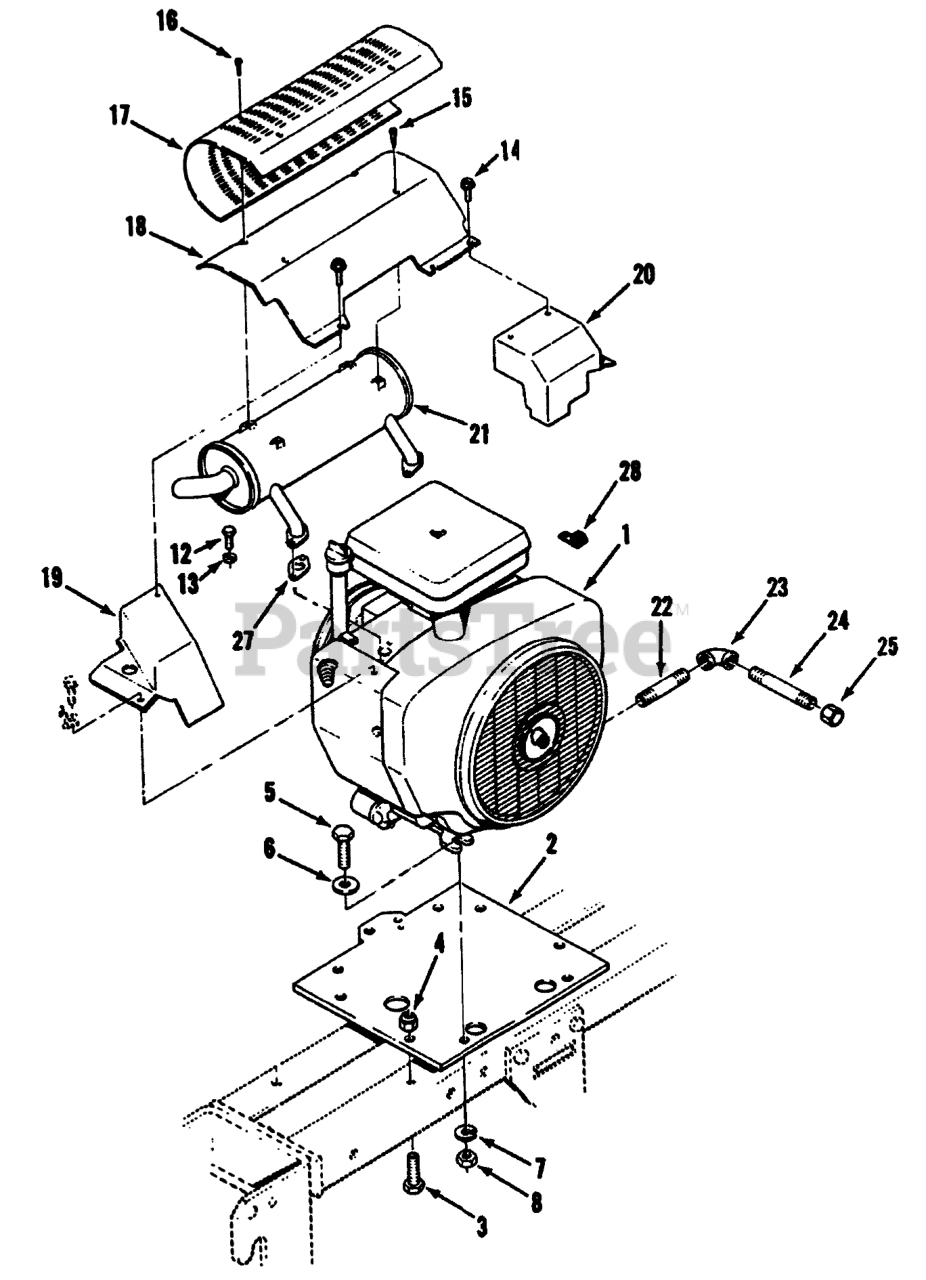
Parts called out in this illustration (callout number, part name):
1	Engine-20HP
2	PLATE-ENGINE B
3	NUT-LOCK, NI
4	SCREW-HH
5	WASHER-FLAT
6	WASHER-FLAT
7	NUT-HEX
8	SCREW-HH
12	SCREW-HH
13	WASHER-LOCK
14	HEX WASHER HD SCREW
15	Screw
17	Shield
18	Air Deflector
19	COVER EXHAUST LH
20	COVER EXHAUST RH
21	MUFFLER-EXHAUST
22	NIPPLE-PIPE
23	ELBOW 3/8 90 DEG
24	PIPE-NIPPLE 3/8 X 4"
25	Cap
27	Gasket-Exhaust
28	CLIP
